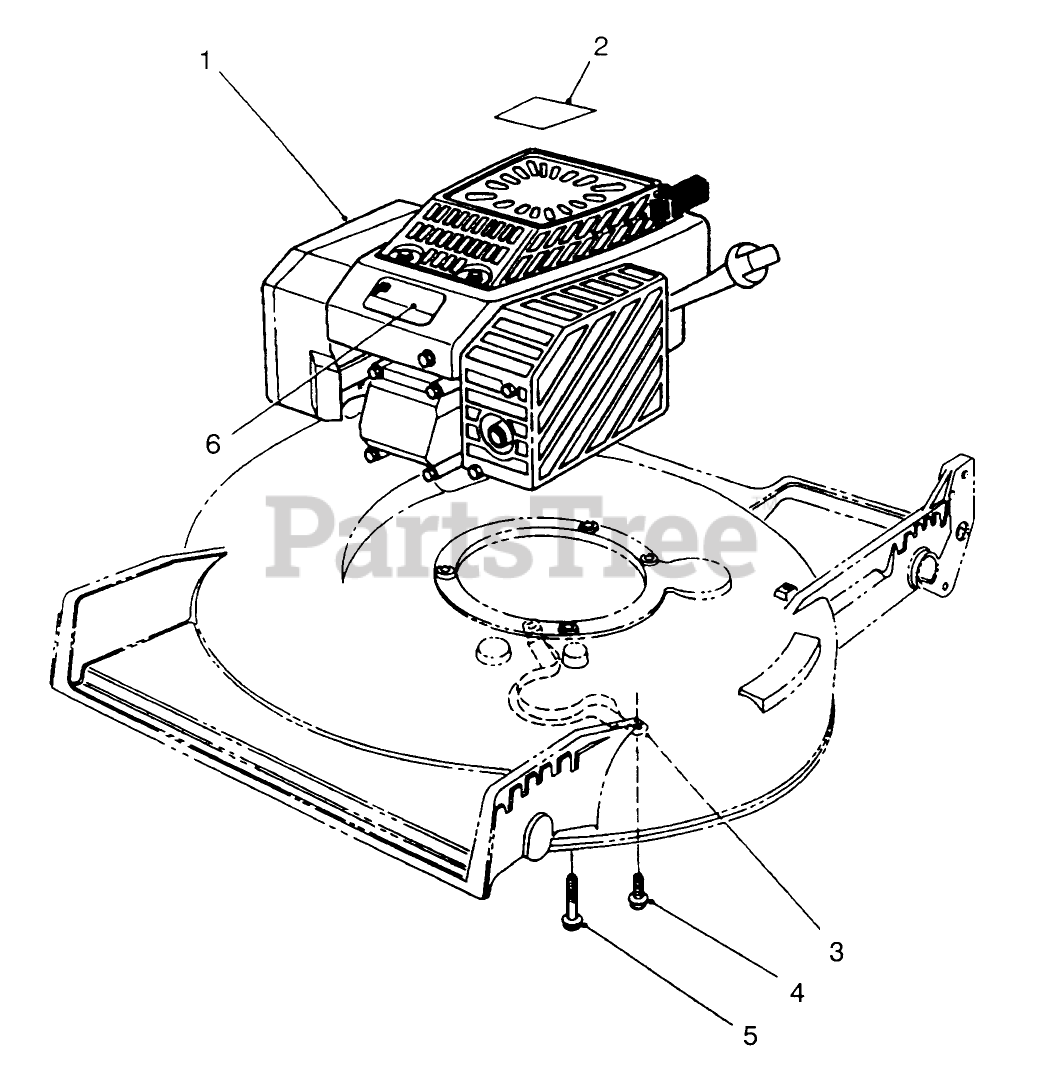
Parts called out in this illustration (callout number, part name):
1	Engine Complete(Incl Ref. #2,6)
2	DECAL - ENGINE
3	Guide-Belt
4	SCREW-HWHTF
5	SCREW-HWH
6	DECAL - PROLINE
